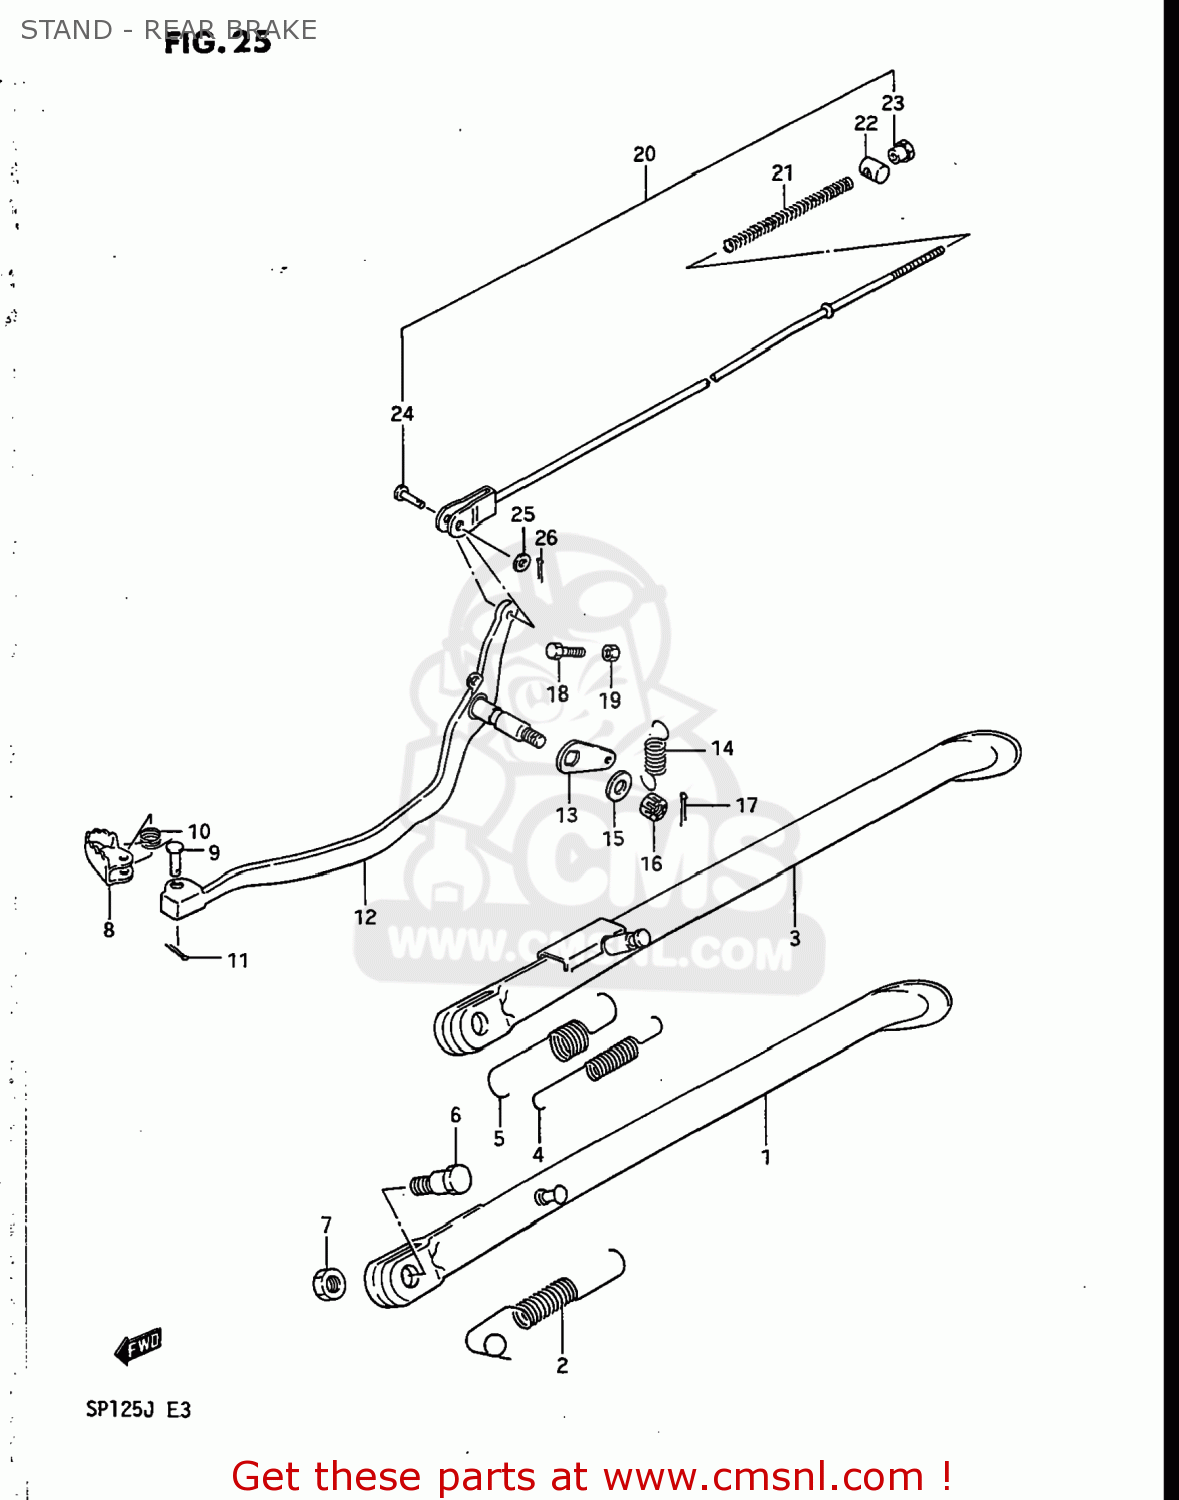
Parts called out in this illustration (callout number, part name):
1	STAND,SIDE
2	SPRING
3	STAND,SIDE
4	SPRING
5	SPRING
6	BOLT L:30
7	NUT
8	PEDAL,BRAKE
9	PIN
10	SPRING
11	PIN
12	ARM,BRAKE PEDAL
13	ARM,BRAKE RETURN SPRING
14	SPRING
15	WASHER
16	NUT 8MM
17	PIN 20X20
18	BOLT(6X23)
19	NUT 6MM
20	ROD ASSEMBLY,REAR BRAKE
21	SPRING
22	PIN
23	NUT (6MM)
24	PIN(L:13.5)
25	WASHER
26	PIN 20X20
